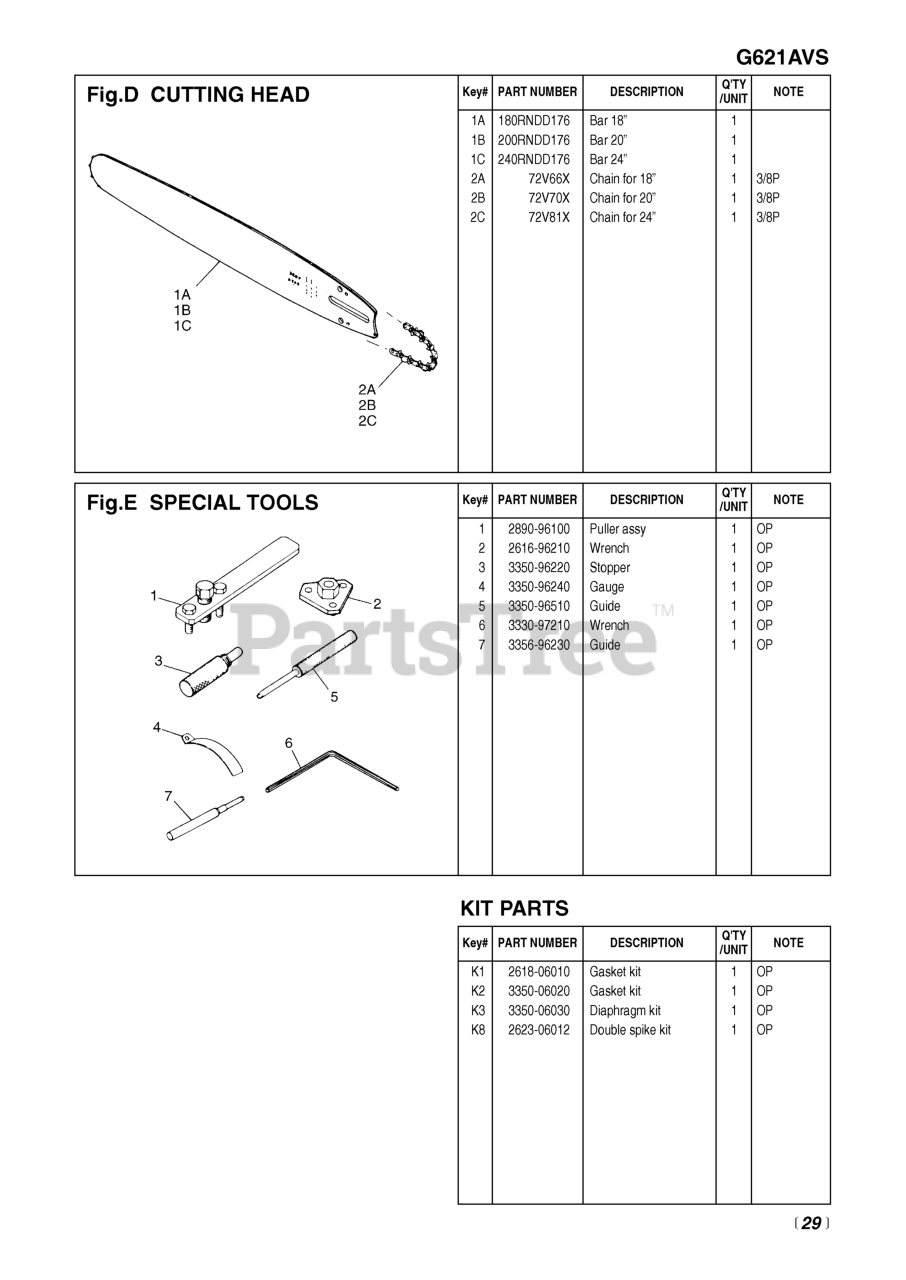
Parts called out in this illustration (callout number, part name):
1	PULLER ASSY
1A	18
1B	20
1C	24
2	WRENCH, CLUTCH (TOOL)
2A	CHAIN FOR 18
2B	CHAIN FOR 20
2C	CHAIN FOR 24
3	STOPPER (TOOL) (RPLS 3320-9641
4	GUAGE, AIR GAP (TOOL)
5	GUIDE, BRAKE SP (TOOL)
6	WRENCH (TOOL)
7	GUIDE (TOOL)
NI	KIT, GASKET
NI	KIT, DIAPHRAGM
NI	DOUBLE SPIKE KIT
